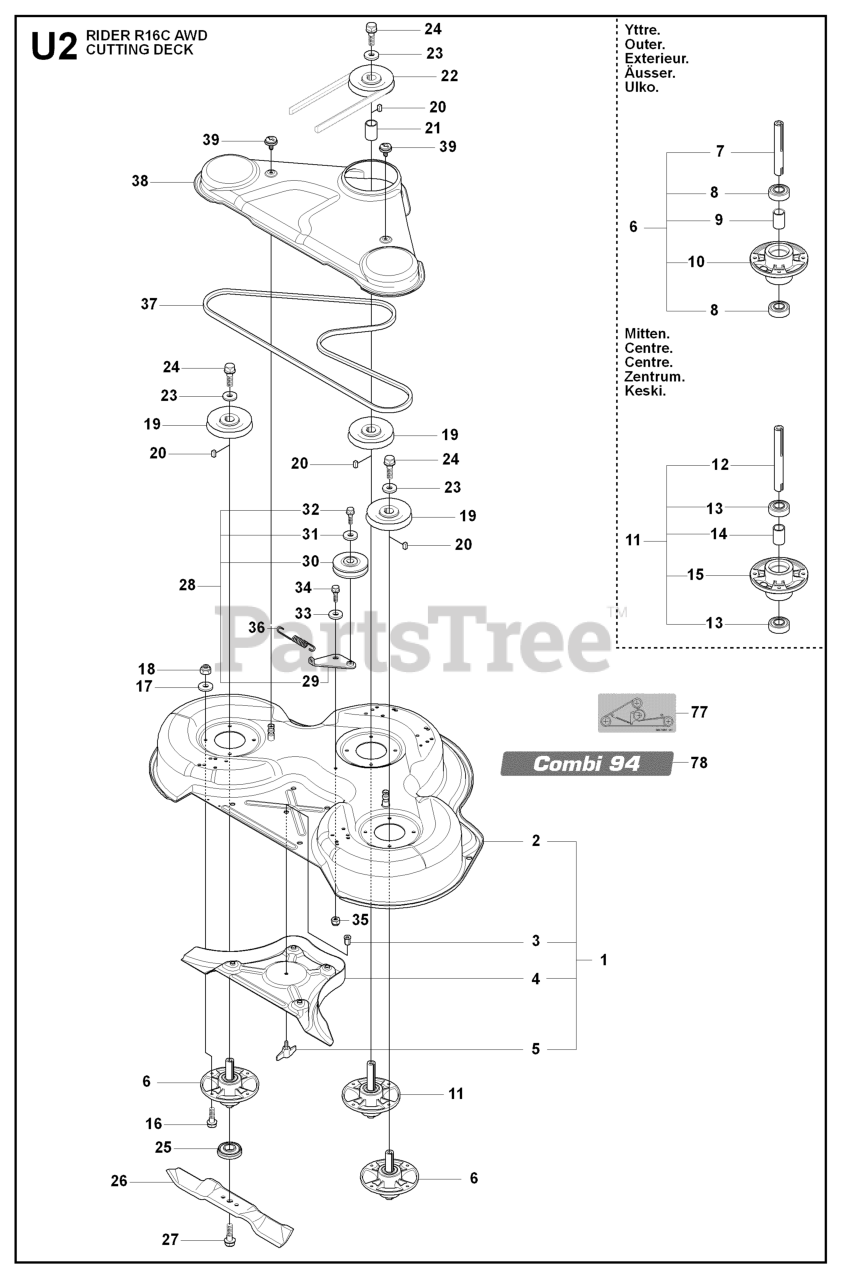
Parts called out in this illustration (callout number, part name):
4	PLUG C93 & C94
6	RP SPINDLE ASSY
10	BEARING HOUSING
15	BEARING HOUSING
17	WASHER BRB 8.4X17
18	LOCKNUT M8
21	SPACING SLEEVE
25	BLADE BRACKET
30	PULLEY
33	WASHER
35	LOCKNUT M8
